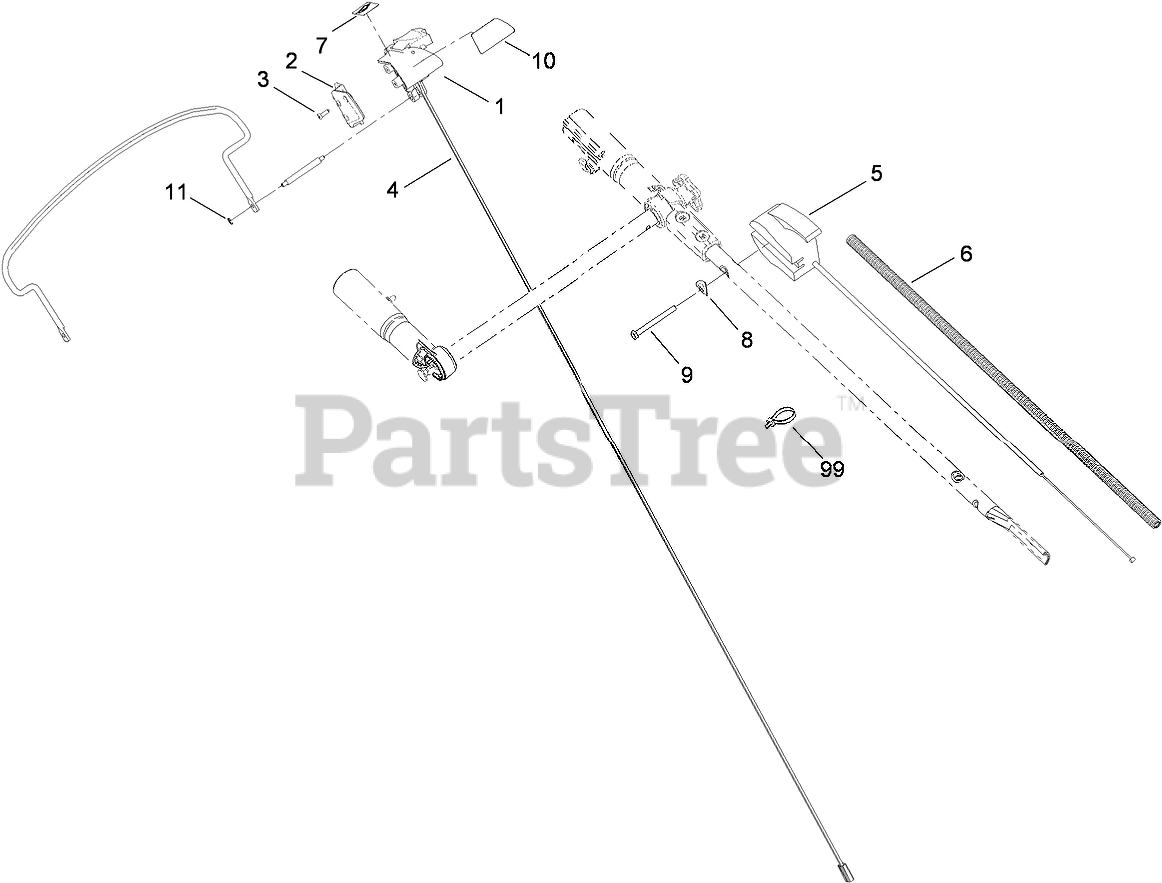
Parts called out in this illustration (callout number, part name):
1	SAFTEY SWITCH ASM
2	COVER-SWITCH
3	SCREW-PPH
4	CABLE-BCS
5	CABLE-THROTTLE
6	CONDUIT
7	DECAL-BLADE
8	WASHER
9	SCREW-HH
10	DECAL-CONTROL, BLADE
11	RING-RETAINING
99	TIE-CABLE
